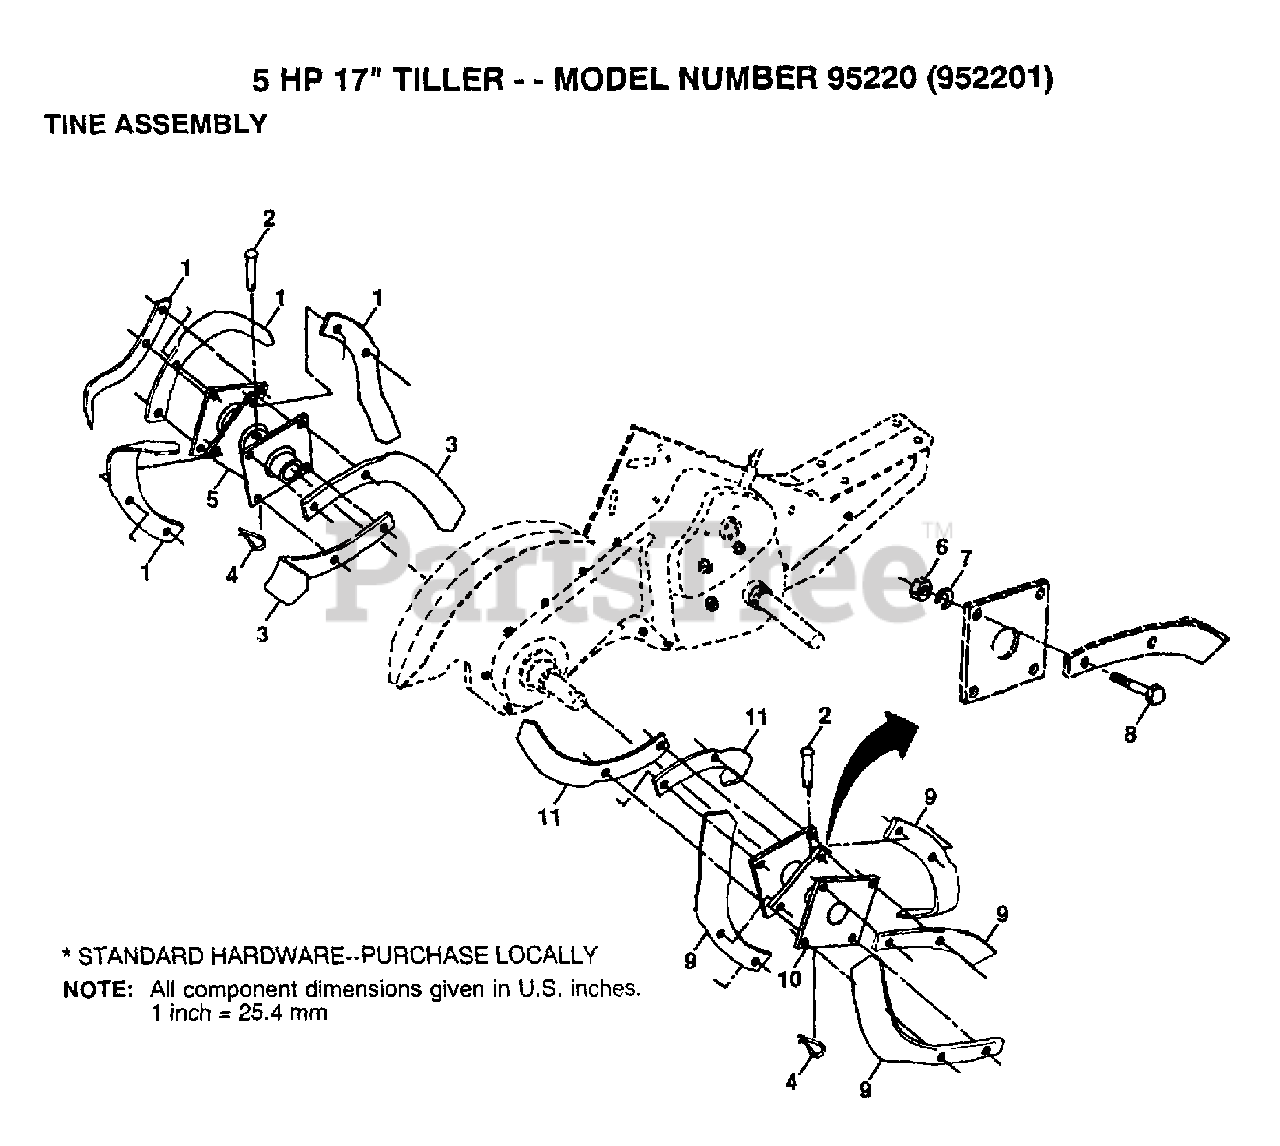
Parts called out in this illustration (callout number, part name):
2	PIN.CLEVIS.SHEAR
3	"TINE.LH.12"""
4	RETAINER.SPRING
5	HUB&PLATE ASM LH
7	LOCKWASHER
8	BOLT
10	HUB&PLATE ASM RH
11	"TINE.RH.12"""
